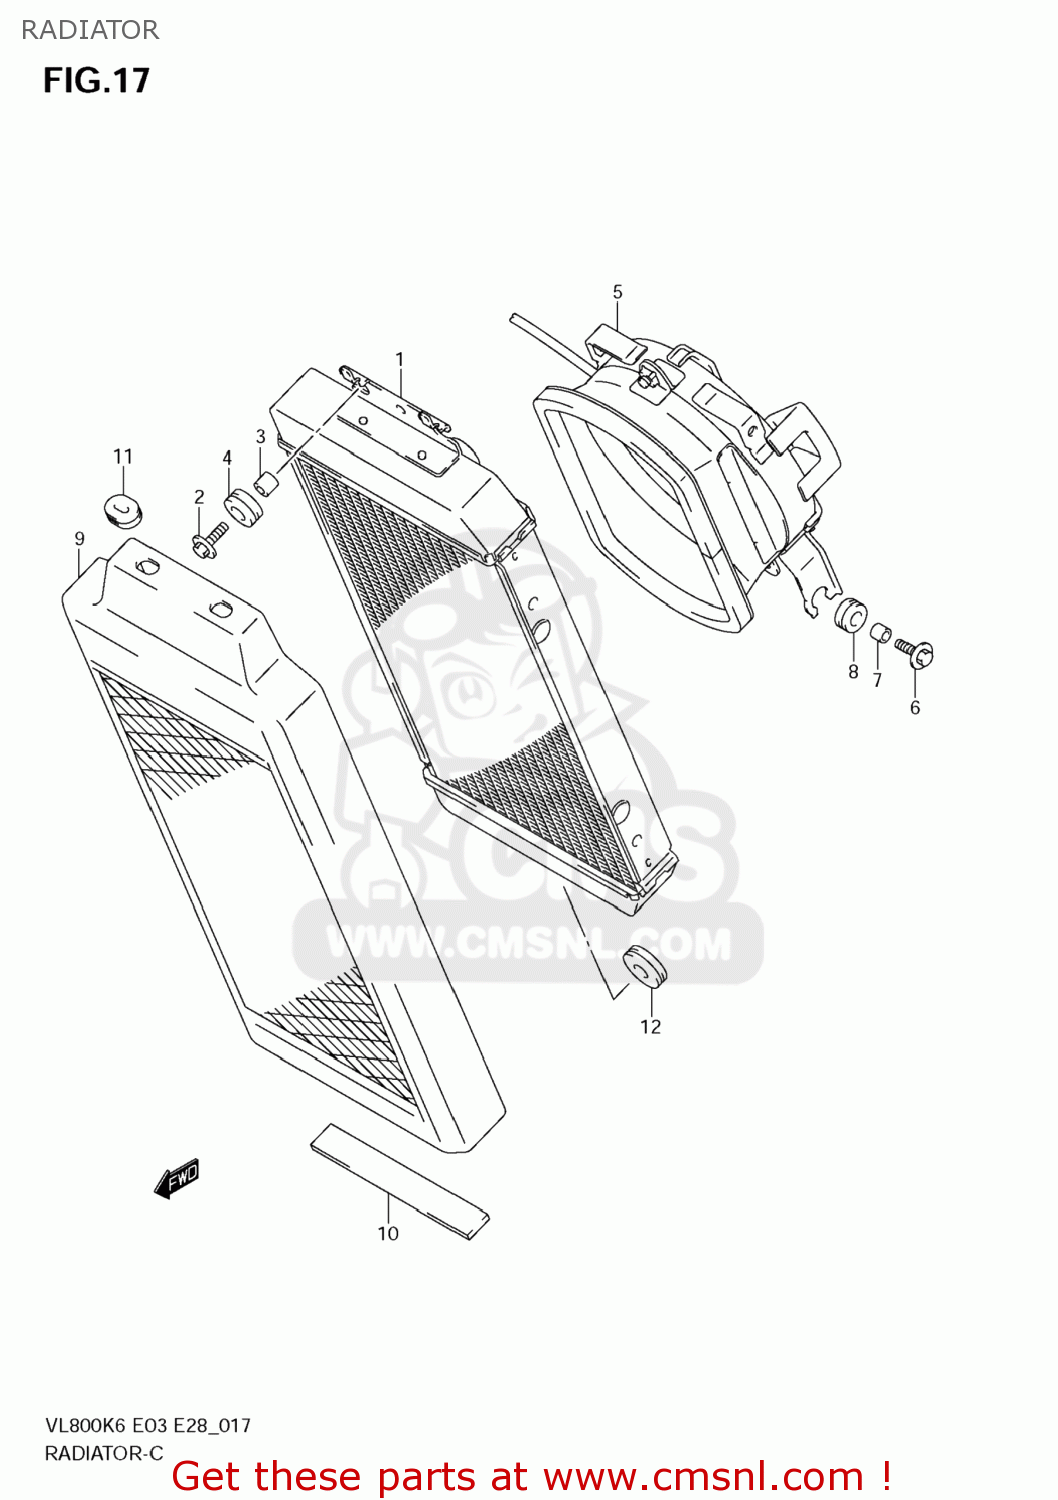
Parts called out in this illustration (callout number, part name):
1	RADIATOR ASSY,WATER
2	BOLT(6X20)
3	SPACER(6.5X10X10)
4	CUSHION
5	FAN ASSY,RADIA
6	BOLT(6X20)
7	SPACER(6.5X10X10)
8	CUSHION
9	COVER,RADIATOR
10	CUSHION,RADIATOR COVER INNER
11	CUSHION
12	CUSHION
